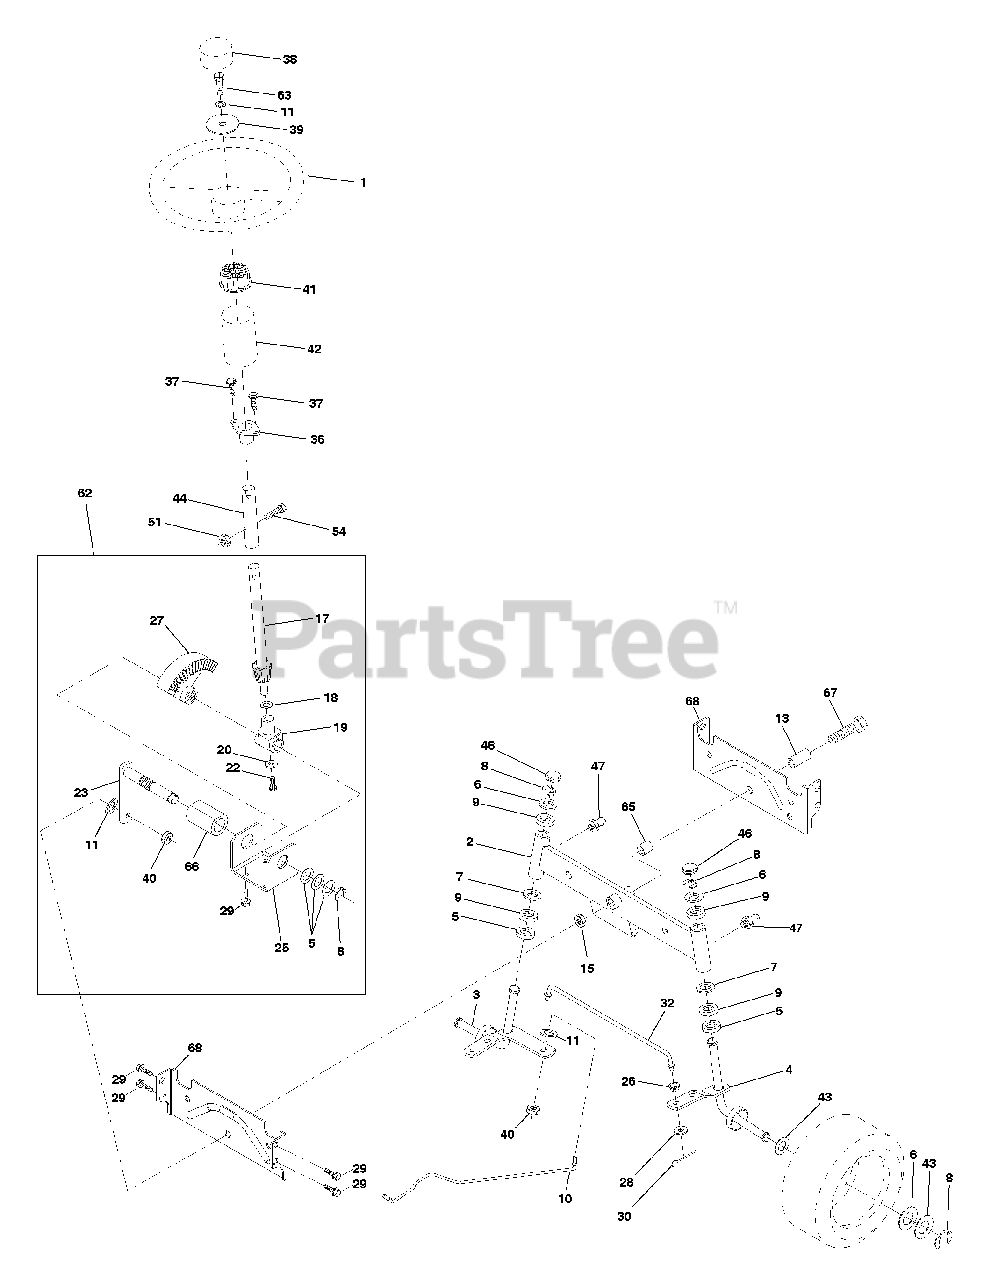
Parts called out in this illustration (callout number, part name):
1	Wheel Steering
2	Axle Asm STMP Dropped STL
3	Spindle Asm LH
4	Spindle Asm RH
5	Bearing Race Thrust Harden
6	Washer 25/32 X 1-5/8 X 16 Ga
7	Washer 27/32 X 1-1/4 X 16 Ga
8	Ring Klip #t5304-75
9	Bearing Col Strg Blk
10	Link Drag Extended Stamp
11	Washer Lock Hvy Hlcl Spr 3/8
13	Bearing Axle STLT/GT
15	Nut Lock Flange 5/8-11 Unc
17	Shaft Asm Strg
18	Washer Thrust 515 x 750 x 033
19	Support Shaft
20	Washer Shim 1/4 X 5/8 X 062
22	Screw Hex Socket 1/4-20 x 5/8
23	Shaft Asm Pittman
25	Bracket Steering
26	Bushing Link Drag Blk LR
27	Gear Sector
28	Washer 13/32 X 7/8 X 16 Ga
29	Screw Thdrol 3/8-16 x 3/4 Ty-tt
30	Pin Cotter 1/8 X 3/4 Cad
32	Rod Tie Wire Form 19 75 Mech
36	Bushing Strg
38	Insert Cap Strg Wh Au
39	Washer 13/32 X 2-3/8 X 8 Ga
40	Lock nut
41	Adaptor Wheel Strg
42	Boot Steering Shaft
43	Washer 25/32 X 1 1/4 X 16 Ga
44	Extension Steering Shaft LR/LT
46	Cap Spindle Fr Top Blk
47	Fitting Grease
51	Nut Lock Hex w/Ins 5/16-18
54	Bolt Fin Hex 5/16-18 Unc x 1-1/4
62	Kit, Steering Assembly Svc
63	Bolt Fin Hex 3/8-16 unc x 1 Gr. 5
65	Spacer Axle
66	Bearing Arm Pittman
67	Bolt, Fin Hex 5/8-11 UNC x 2-3/4
68	Axle, Brace
